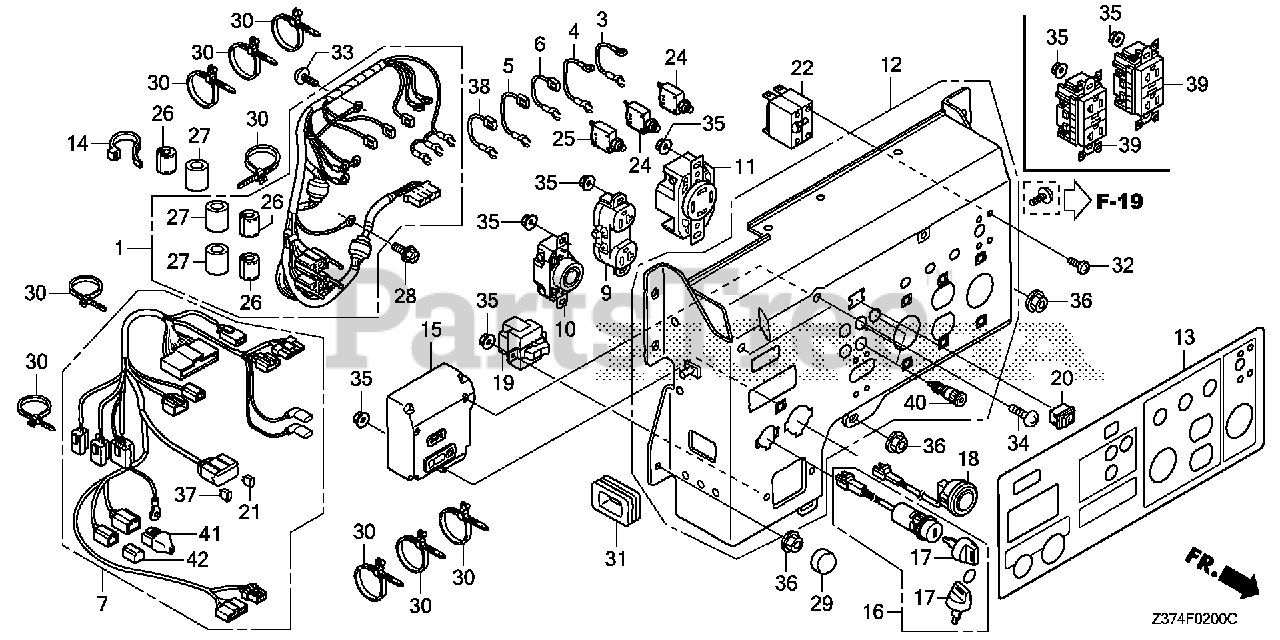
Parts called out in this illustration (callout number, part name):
1	WIRE HARNESS ASSY., MAIN
3	SUB-WIRE ASSY. (A)
4	SUB-WIRE ASSY. (B)
5	SUB-WIRE ASSY. (E)
6	SUB-WIRE ASSY. (D)
7	WIRE HARNESS ASSY., CONTROL
10	RECEPTACLE (30A-125V)
10	RECEPTACLE (3-PRONG) (30A/125V)
11	RECEPTACLE (30A/125-250V)
11	RECEPTACLE (30A-125/250V)
12	PANEL, CONTROL
13	MARK, PANEL
14	BAND, TUBE (NOT AVAILABLE)
15	UNIT ASSY,GENERAT
15	CONTROL UNIT, GENERATOR
16	SWITCH ASSY., COMBINATION
17	KEY ASSY., COMBINATION SWITCH (RED)
18	SWITCH ASSY., START
19	SWITCH ASSY., VOLT CHANGE
20	SWITCH, AUTO-THROTTLE (OTAX)
21	FUSE, BLADE (3A)
22	PROTECTOR, CIRCUIT (30A)
24	PROTECTOR, CIRCUIT (20A) (WHITE)(TYCO)
24	PROTECTOR, CIRCUIT (20A) (BLACK)(JOEMEX)
25	PROTECTOR, CIRCUIT (30A) (WHITE)
25	PROTECTOR, CIRCUIT (30A) (BLACK)
26	FILTER, SUB NOISE (AC)
27	SUPPORTER, FILTER
28	SCREW, TAPPING (5X12)
29	CAP, BOLT (6MM)
30	STRAP, CABLE (105MM) *NH1* (Honda Code 1685536). (BLACK)
31	GROMMET, CONTROL HARNESS
32	SCREW, PAN (3X5) (NOT AVAILABLE)
33	SCREW, PAN (5X8)
34	SCREW, PAN (5X12)
35	NUT, FLANGE (4MM)
36	NUT, FLANGE (6MM)
37	FUSE, BLADE (15A)
38	SUB-WIRE ASSY. (F)
39	RECEPTACLE (20A-125V) (GFCI)
40	SOCKET, COMPOSITE
41	CONNECTOR ASSY., SHORT
42	CONNECTOR, DUMMY (4P)
